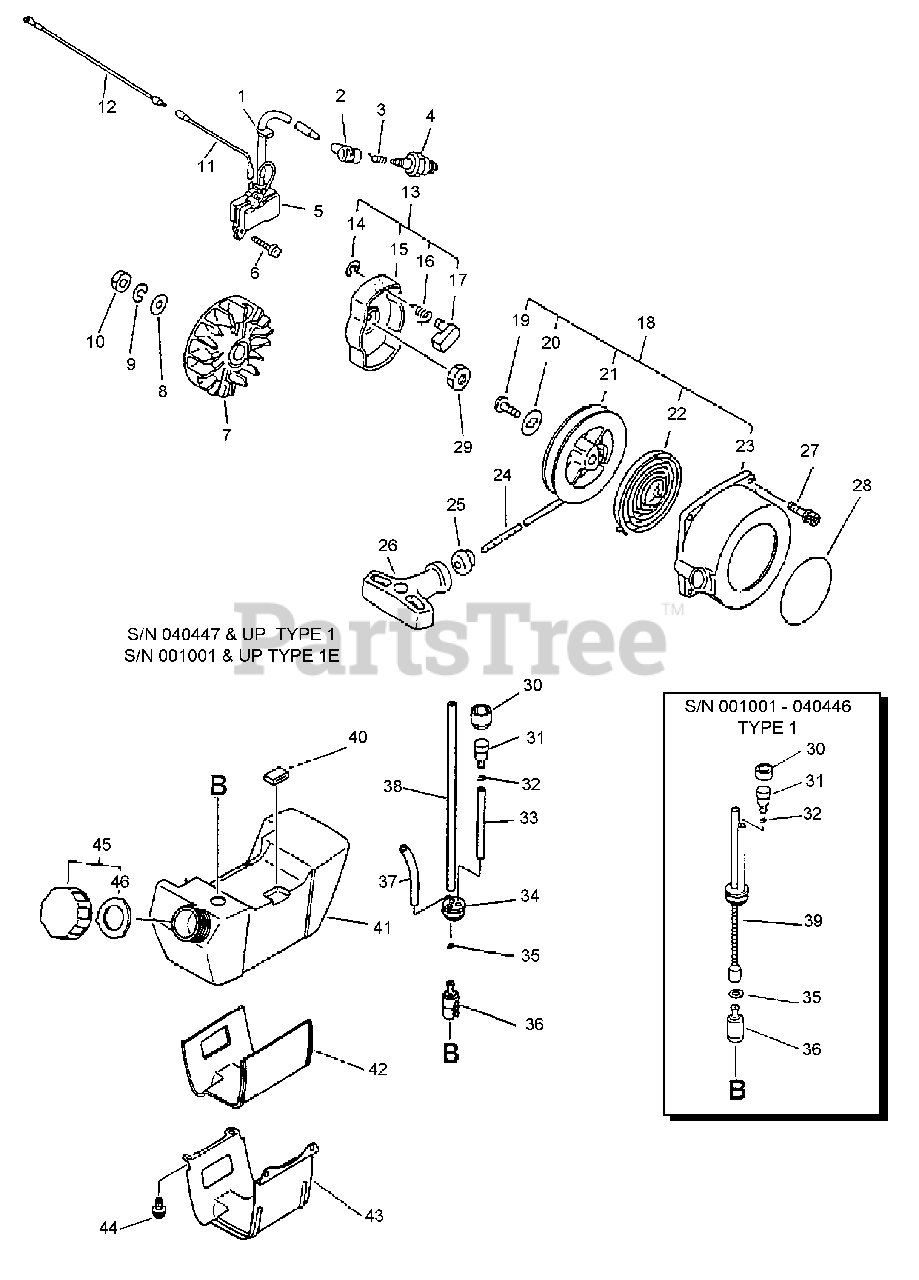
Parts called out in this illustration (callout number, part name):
2	CAP, SPARK PLUG
3	TERMINAL, SPARK PLUG CAP
4	SPARK PLUG -- BPM-7A
5	COIL, IGNITION
6	SCREW - 5X20
7	FLYWHEEL
8	WASHER - 10
9	LOCKWASHER - 10
10	NUT - 10
11	LEAD - IGNITION
12	LEAD - GROUND
13	STARTER PAWL ASSY
14	RING, RETAINING - 4
15	CATCHER, PAWL
16	SPRING, RETURN
17	PAWL, STARTER
18	STARTER ASSY
21	REEL, ROPE
22	SPRING, REWIND
23	CASE, STARTER - ORANGE
24	ROPE, STARTER - 4X950
25	GUIDE, ROPE
26	GRIP, STARTER
27	SCREW - 4X20
28	LABEL - ECHO
30	COVER, VENT
31	VENT, FUEL TANK
32	CLIP - 5.5
33	PIPE - 3X6X70 -- BLACK
34	GROMMET
35	WASHER - 5
35	CLIP - 6
36	FILTER, FUEL
37	PIPE - 3X6X90 -- CLEAR
38	PIPE - 3X5X180 -- BLACK
39	FUEL PIPE ASSY
41	TANK, FUEL
43	BRACKET, FUEL TANK
44	SCREW - 5X14
45	CAP ASSY
46	GASKET, CAP
